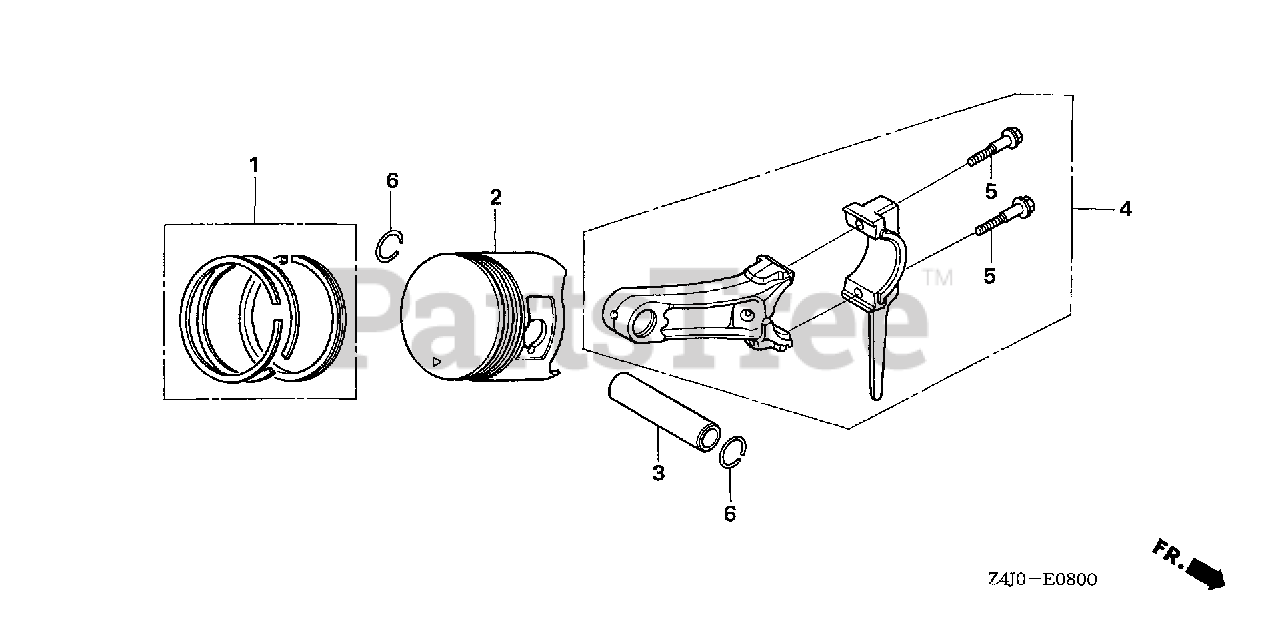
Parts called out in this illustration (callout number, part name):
1	RING SET, PISTON (STD) (TEIKOKU)
1	RING SET, PISTON (STD.) (NIPPON)
1	RING SET, PISTON (STD) (TPR)
1	RING SET, PISTON (OS 0.25) Use from Engine SN 7603339.
1	RING SET, PISTON (0.25) (NIPPON) Use up to Engine SN 1314912.
1	RING SET, PISTON (0.25) Use from Engine SN 1314913.
1	RING SET, PISTON (OS 0.50) Use from Engine SN 7603339.
1	RING SET, PISTON (0.50) (NIPPON) Use up to Engine SN 1314912.
1	RING SET, PISTON (0.50) (TPR)
1	RING SET, PISTON (0.75) (TEIKOKU) Use up to Engine SN 1314912.
1	RING SET, PISTON (0.75) (NIPPON) Use up to Engine SN 1314912.
1	RING SET, PISTON (0.75) Use from Engine SN 1314913.
2	PISTON (STD)
2	PISTON (OS 0.25) Use from Engine SN 7603339.
2	PISTON (0.25) Use from Engine SN 1314913.
2	PISTON (0.50) Use up to Engine SN 1314912.
2	PISTON (0.50) Use from Engine SN 1314913.
2	PISTON (0.75) Use up to Engine SN 1314912.
2	PISTON (0.75) Use from Engine SN 1314913.
3	PIN, PISTON
4	ROD ASSY., CONNECTING
5	BOLT, CONNECTING ROD
6	CLIP, PISTON PIN (18MM)
